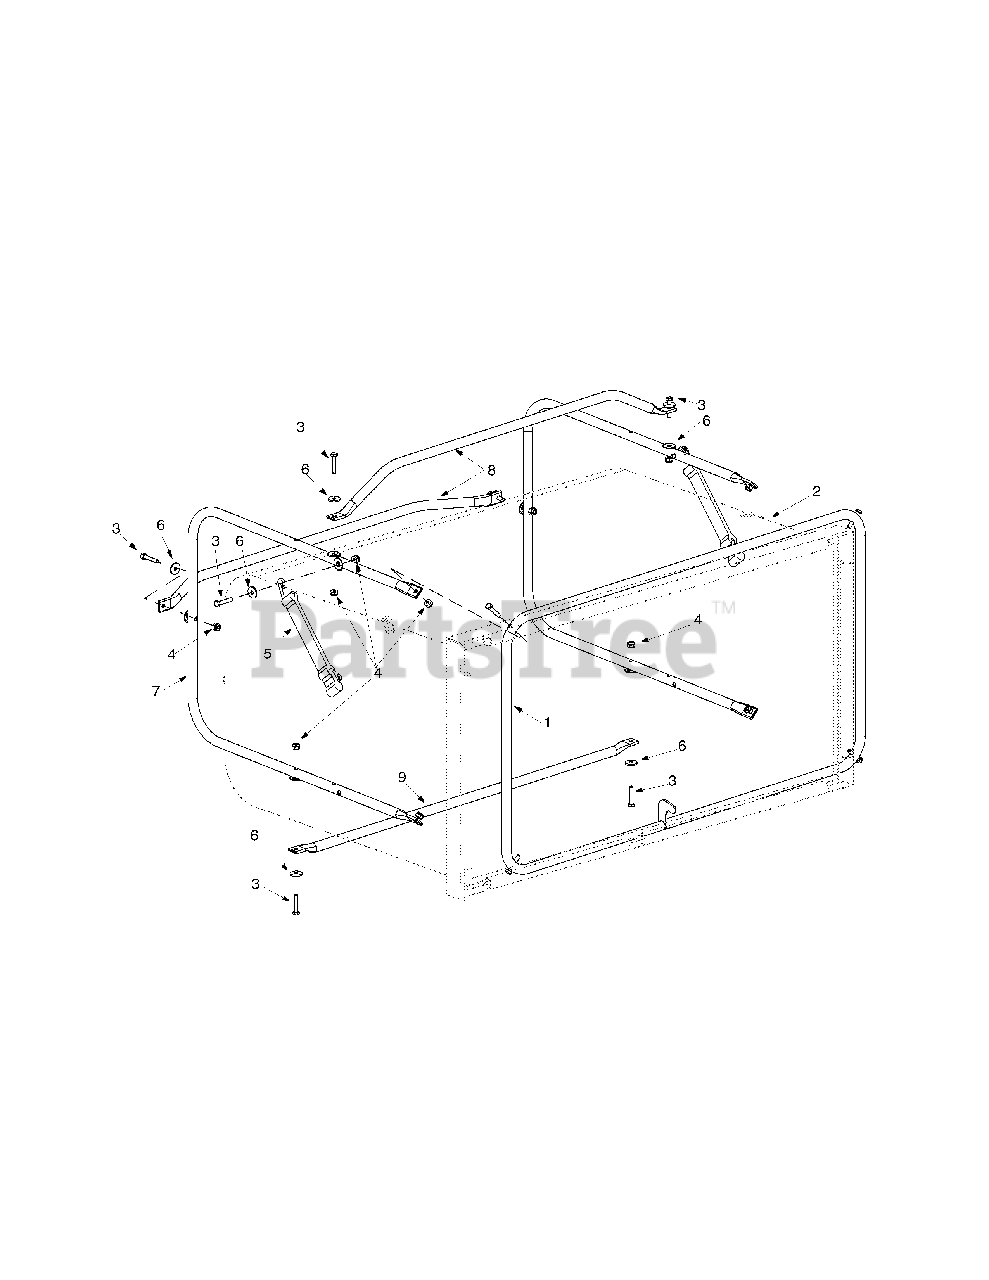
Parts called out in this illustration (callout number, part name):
1	Tube Assembly: Front Frame
2	Grass Catcher Bag
3	Mach. Screw #10-24 x 1.0
4	Lock Nut #10-24
5	Retainer Strap
6	Flat Washer
7	Side Tube: Frame
8	Bag Handle
9	Support Tube
